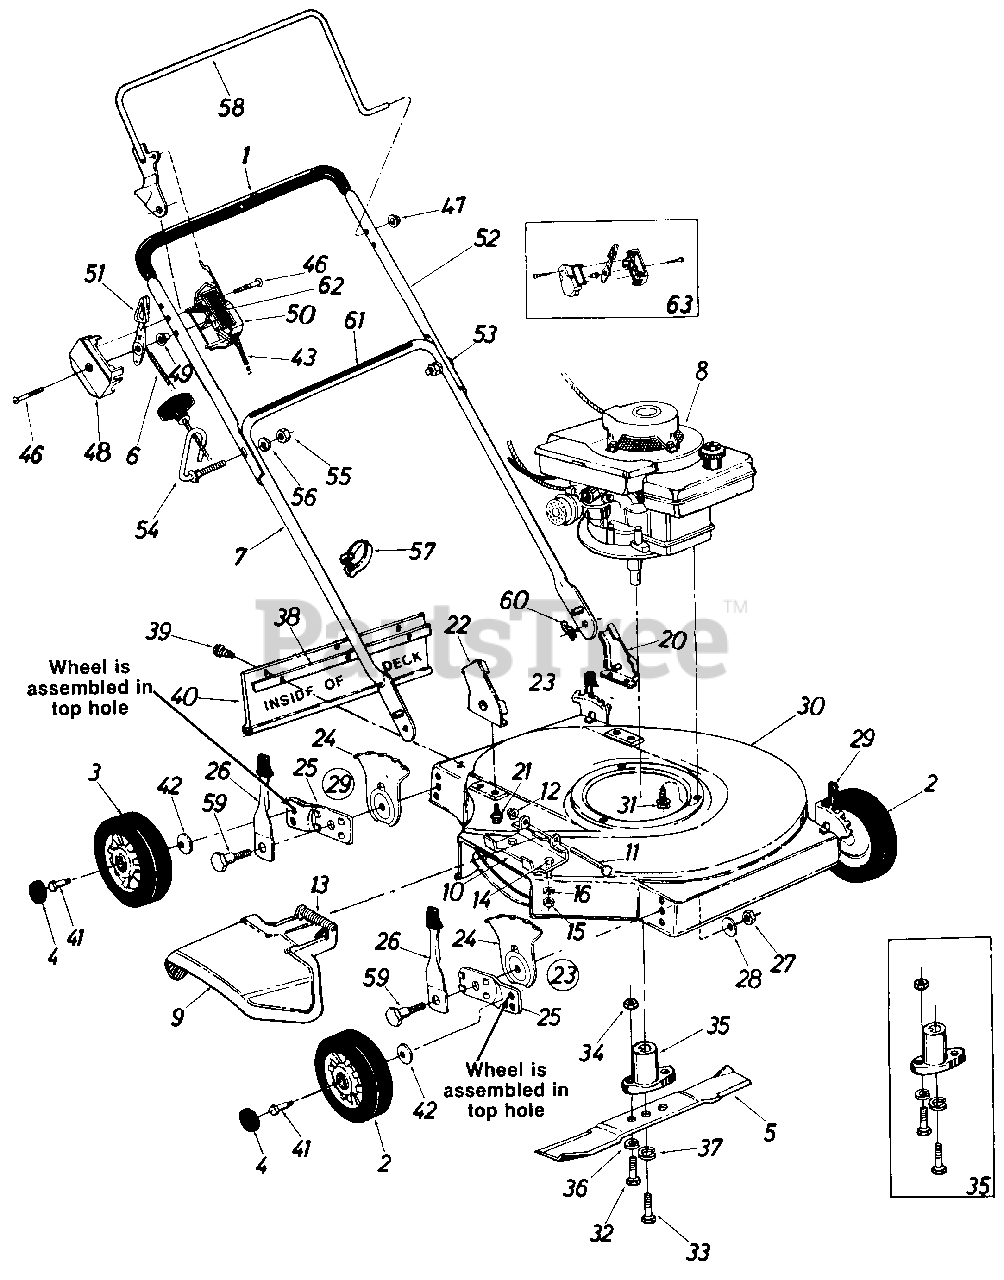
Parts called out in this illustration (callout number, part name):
2	Front Wheel Ass'y. Comp. 8 x 1.75
3	Rear Wheel Ass'y. Comp. 8 x 1.75
4	Hub Cap
5	20" Blade
6	Throttle Wire 45"
7	Lower Handle
9	Chute Deflector Ass'y. Comp
10	Adapter Plate
11	Pivot Pin
12	Push Cap 1/4" Rod
13	Torsion Spring
14	Hex Bolt 1/4-20 x .50" Lg.
15	Hex Nut 1/4-20 Thd.
16	L-Wash. 1/4" I.D.
20	Handle Brk't. Ass'y. L.H.
21	Hex Wash. Hd. B-Tap Scr. 5/16-18 x .50" Lg.
22	Handle Brk't. Ass'y. R.H.
23	Height Adjuster Ass'y. Comp. R.H.
24	Index Plate
25	Pivot Bar
26	Spring Lever Ass'y. w/Knob
27	Hex Nut 3/8-16 Thd.
28	Bell-Wash. .39" I.D. x 1.13" O.D.
29	Height Adjuster Ass'y. Com p. L.H.
30	20" Deck Ass'y. Comp.
31	Hex Wash. Hd. TT-Tap Scr. 3/8-16 x 1.0" Lg.
32	Hex Bolt 5/16-18 x 1.0" Lg. (Grade 8)
33	Hex Bolt 3/8-24 x 2.25" Lg. Grade 5
34	Hex Nut 5/16-24 Thd.
35	Blade Adapter Kit
36	L-Wash. 5/16" I.D.
37	L-Wash. 3/8" I.D. H.D.
38	Retaining Strip
39	Hex Wash. Hd. AB-Tap Scr. 1/4" x .62" Lg.
40	Rear Flap Ass'y.
41	Shld. Bolt .498" Dia. x 1.45"
42	Bell-Wash. .400" I.D. x .88" O.D.
43	Control Cable 43"
46	Truss Mach. Self-Tap Scr. #12 x 1.5" Lg.
47	Push Cap 5/16" Rod
48	Control Panel Half
49	Control Disc Pin
50	Clutch Panel Half
51	Throttle Control Lever
52	Upper Handle
53	Curved Carriage Bolt 5/16-18 x 1.38" Lg.
54	Rope Guide Bolt
55	Hex Nut 5/16-18 Thd.
56	L-Wash. 5/16" I.D.
57	Cable Tie
58	Control Handle Ass'y. R.H.
59	Shld. Bolt .500" Dia. x .375
60	Hairpin Cotter
61	Instruction Label Handle
62	Control Label Throttle
63	Kit Control Housing Comp.
